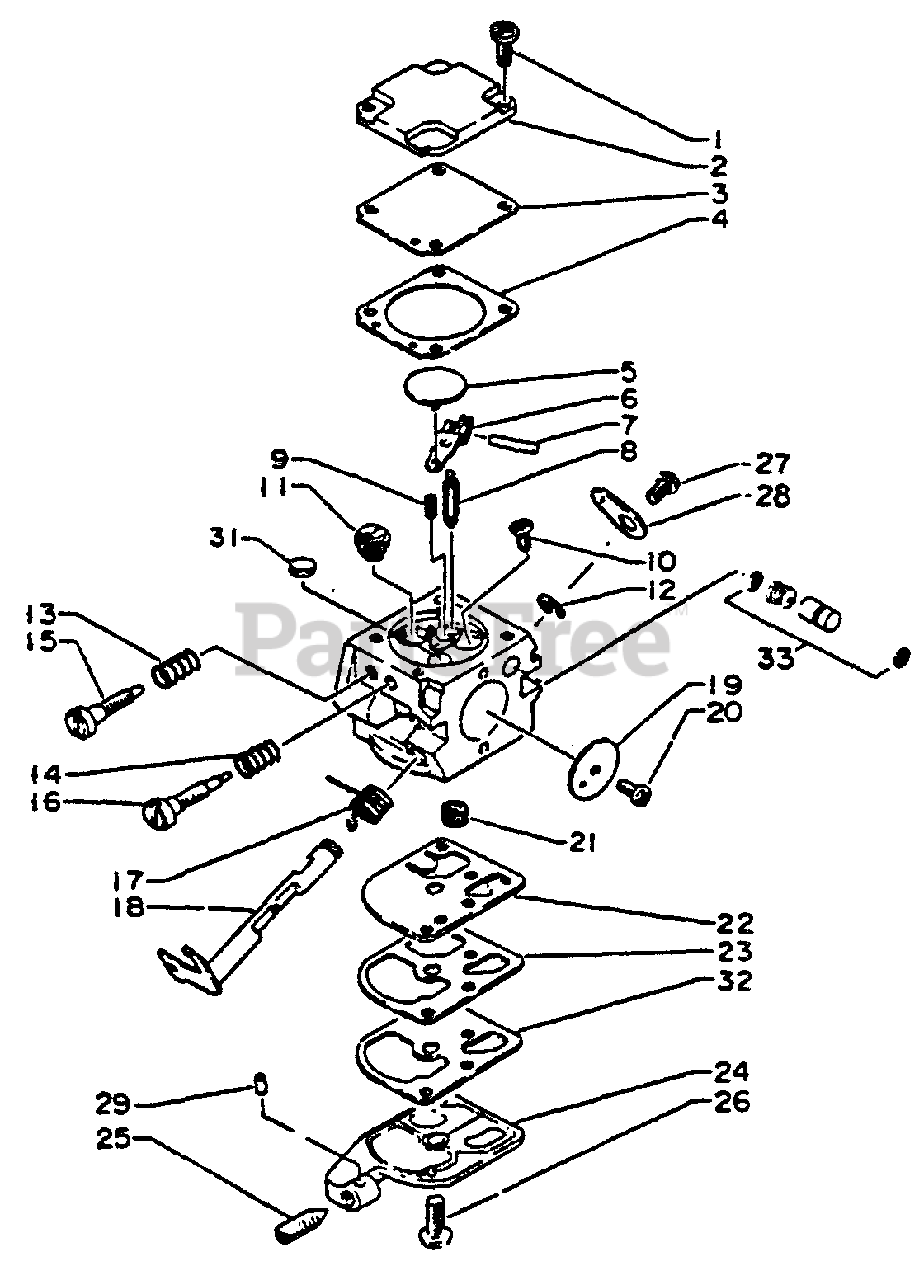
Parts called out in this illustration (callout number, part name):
2	COVER, DIAPHRAGM
3	DIAPHRAGM
4	GASKET, METERING
5	DISK
6	LEVER, METERING
7	PIN, METERING LEVER
9	SPRING, METERING LEVER
13	SPRING
15	NEEDLE, HIGH SPEED
16	NEEDLE, IDLE
17	SPRING, THROTTLE RETURN
18	SHAFT ASSY, THROTTLE
19	VALVE, THROTTLE
20	SCREW
21	STRAINER
24	BASE, PUMP
25	SCREW, IDLE ADJUST
28	LEVER, THROTTLE
29	PIECE, FRICTION
31	PLUG, WELCH
32	DIAPHRAGM, SURGE
33	PUMP KIT
